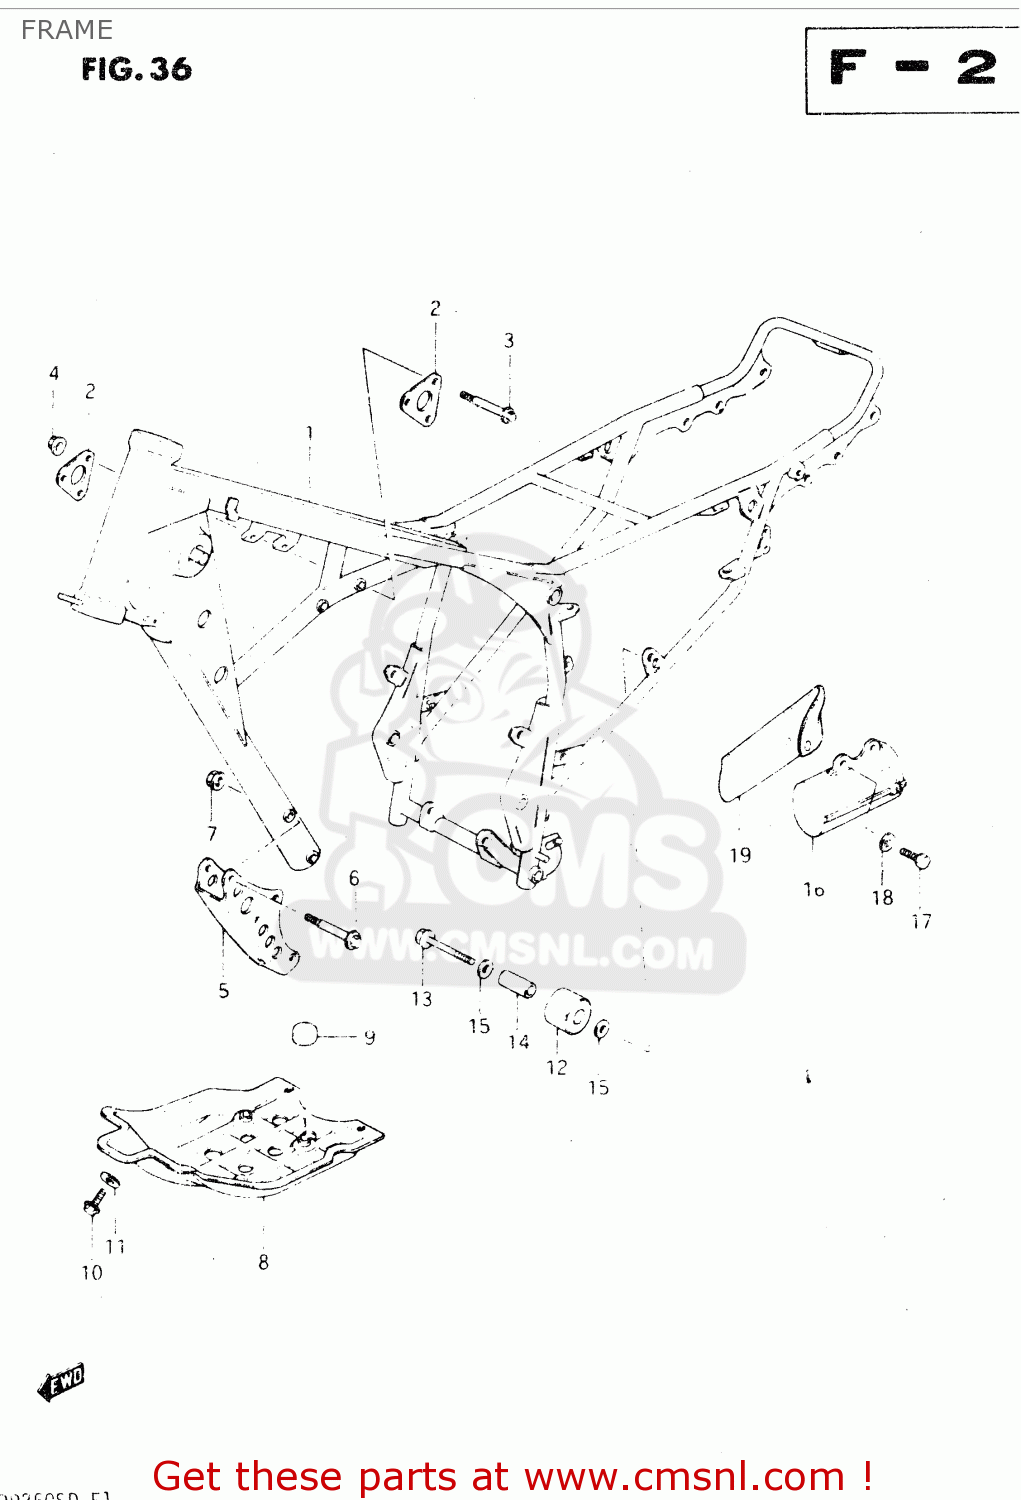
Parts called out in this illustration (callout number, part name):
1	FRAME (BLACK)
2	PLATE,ENGINE MOUNT UPR
3	BOLT
4	NUT
5	PLATE,ENGINE MOUNTING
6	BOLT
7	NUT
8	PROTECTOR,ENGINE
9	CUSHION
10	BOLT
11	WASHER
12	ROLLER,CHAIN LENGTH CONTROL
13	BOLT(8X45)
14	SPACER,CHAIN LENGTH ROLLER
15	WASHER
16	HOLDER,TOOL
17	BOLT, UPPER
18	WASHER (6.5X18X1.6)
19	TOOL ASSY
